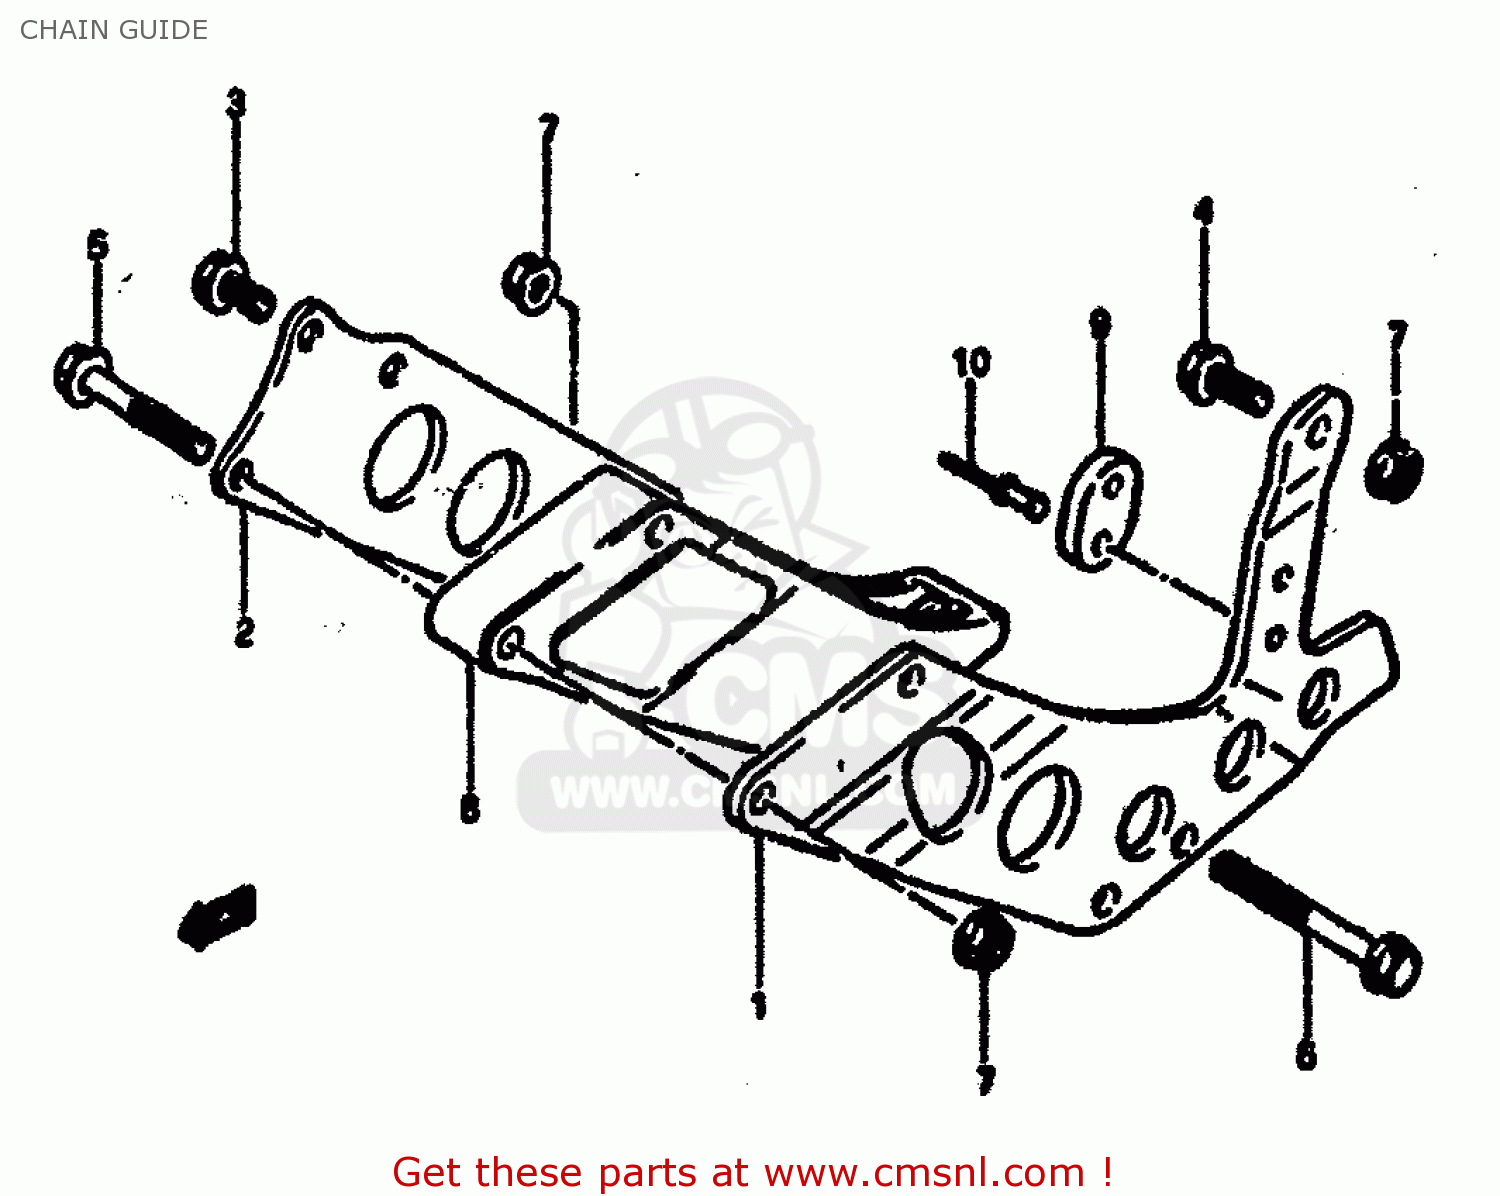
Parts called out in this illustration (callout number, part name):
1	PLATE,CHAIN GUIDE,OUTER
2	PLATE,CHAIN GUIDE,INNER
3	BOLT
4	BOLT
5	BOLT
6	BOLT,UNDER
7	NUT
8	DEFENSE,CHAIN GUIDE
9	PAD,CHAIN GUIDE
10	RIVET
